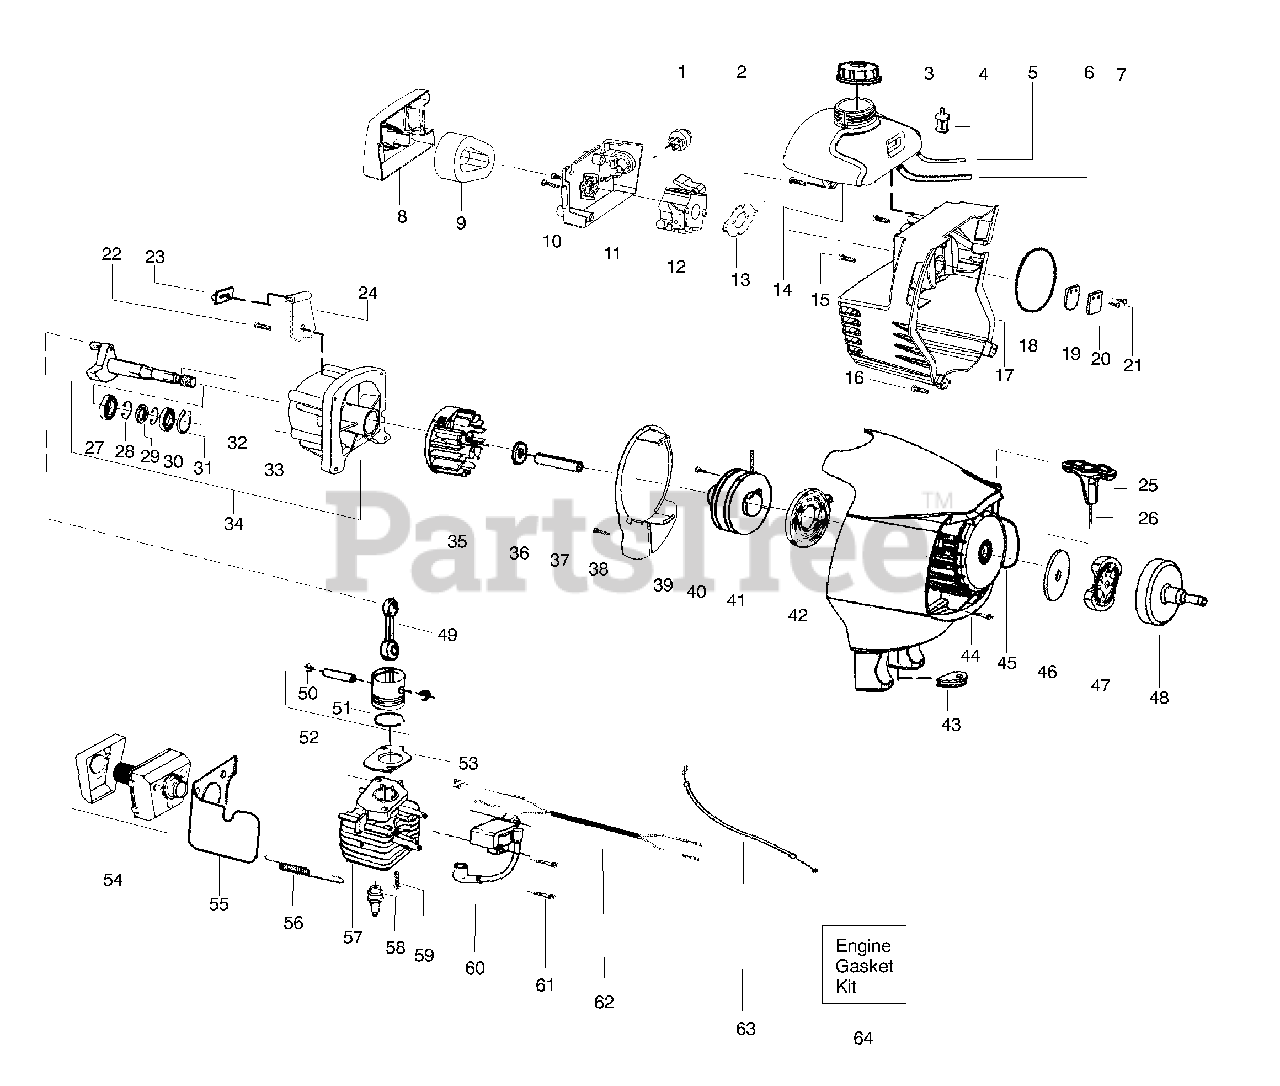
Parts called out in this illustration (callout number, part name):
1	Bulb-purge
2	Screw-tank
3	Assy-Fuel cap
4	Assy-Fuel pick-up
5	Kit-Fuel line
6	Kit-Fuel/Purge line
8	Cover-Air box
9	Filter-Air
10	Screw-carb.
12	Kit-Assy-carb. (WT-619)
12	Kit-Assy-carb. (WT-627)
12	Kit-Assy-carb. (WT-628)
13	Gasket-Carb. (kit)
14	Assy-Fuel tank
15	Screw-crankcase
16	Screw-shrd to f/hsg.
18	O-Ring-c/case (kit)
19	Valve-reed
20	Stop-reed
21	Screw-reed valve
22	Screw-tank retainer
23	Isolator-fuel tank
24	Ret.-fuel tank
25	Handle-starter
26	Kit-Rope
27	Bearing-inner
28	Retainer
30	Bearing-outer
31	Retainer-crankshaft
32	Assy-crankshaft
33	Assy-crankcase
34	Assy-c'case/c'shaft
35	Kit-Flywheel Assy.
38	Screw-baffle
39	Plate-baffle
40	Screw-rope
41	Kit-pulley
42	Spring-starter
44	Screw-F/hsg
45	Housing-Fan w/eyelet
46	Washer-Clutch
47	Assy.-Clutch
48	Assy-Drum
49	Assy-Connecting rod
50	Retainer-piston pin
51	Ring-Piston
52	Kit-Piston
53	Gasket-Cylinder (kit)
54	Kit-Muffler
55	Heat shield/air dam
56	Spring-muffler
57	Kit-Cylinder
58	Spark plug (RCJ-6Y)
59	Bolt-Cylinder
60	Module-Ignition
61	Screw-module
62	Assy-Rear wire
63	Assy-Throttle Cable
64	Kit-Gasket
